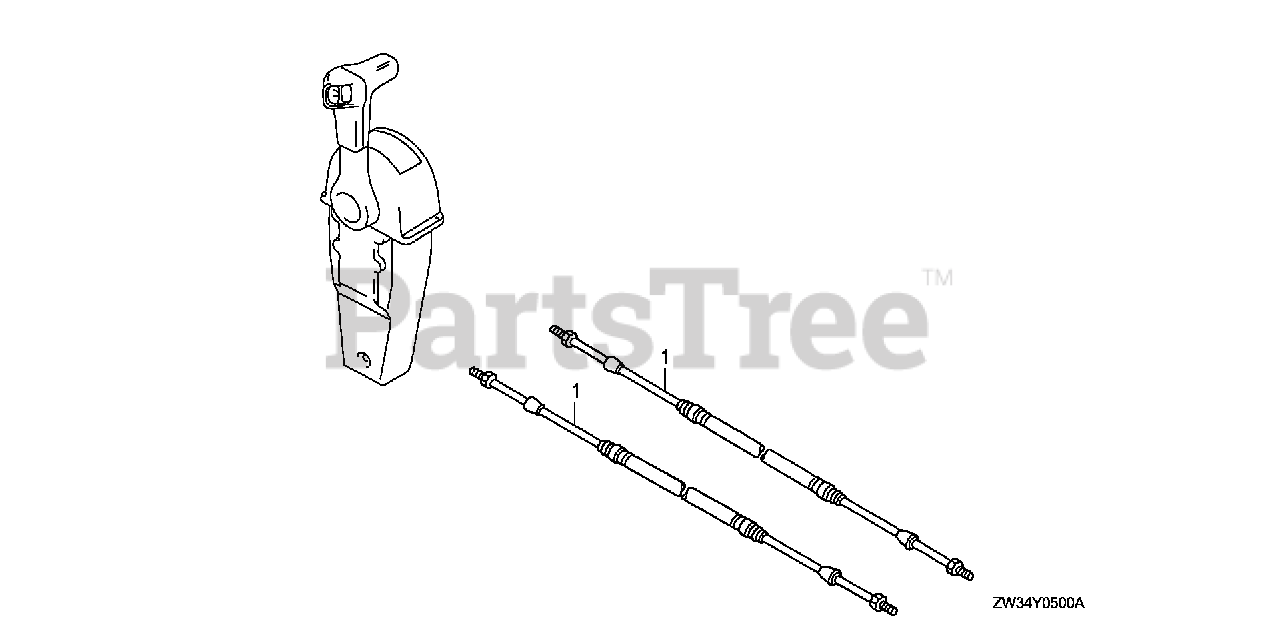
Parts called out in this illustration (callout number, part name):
1	CABLE, REMOTE CONTROL (10') (LOW FRICTION)
1	CABLE ASSY., PUSH-PULL (33C-5FT)
1	CABLE, REMOTE CONTROL (11') (LOW FRICTION)
1	CABLE ASSY., PUSH-PULL (33C-6FT)
1	CABLE, REMOTE CONTROL (12') (LOW FRICTION)
1	CABLE ASSY., PUSH-PULL (33C-7FT)
1	CABLE, REMOTE CONTROL (13') (LOW FRICTION)
1	CABLE ASSY., PUSH-PULL (33C-8FT)
1	CABLE, REMOTE CONTROL (14') (LOW FRICTION)
1	CABLE ASSY., PUSH-PULL (33C-9FT)
1	CABLE, REMOTE CONTROL (15') (LOW FRICTION)
1	CABLE ASSY., PUSH-PULL (33C-10FT)
1	CABLE, REMOTE CONTROL (16') (LOW FRICTION) (NOT AVAILABLE)
1	CABLE ASSY., PUSH-PULL (33C-11FT)
1	CABLE, REMOTE CONTROL (17') (LOW FRICTION)
1	CABLE ASSY., PUSH-PULL (33C-12FT)
1	CABLE, REMOTE CONTROL (18') (LOW FRICTION) (NOT AVAILABLE)
1	CABLE ASSY., PUSH-PULL (33C-13FT)
1	CABLE, REMOTE CONTROL (19') (LOW FRICTION)
1	CABLE ASSY., PUSH-PULL (33C-14FT)
1	CABLE, REMOTE CONTROL (20') (LOW FRICTION) (NOT AVAILABLE)
1	CABLE ASSY., PUSH-PULL (33C-15FT)
1	CABLE, REMOTE CONTROL (21') (LOW FRICTION)
1	CABLE ASSY., PUSH-PULL (33C-16FT)
1	CABLE, REMOTE CONTROL (22') (LOW FRICTION) (NOT AVAILABLE)
1	CABLE ASSY., PUSH-PULL (33C-17FT)
1	CABLE, REMOTE CONTROL (23') (LOW FRICTION)
1	CABLE ASSY., PUSH-PULL (33C-18FT)
1	CABLE, REMOTE CONTROL (24') (LOW FRICTION) (NOT AVAILABLE)
1	CABLE ASSY., PUSH-PULL (33C-19FT)
1	CABLE, REMOTE CONTROL (25') (LOW FRICTION)
1	CABLE ASSY., PUSH-PULL (33C-20FT)
1	CABLE, REMOTE CONTROL (26') (LOW FRICTION)
1	CABLE ASSY., PUSH-PULL (33C-21FT)
1	CABLE, REMOTE CONTROL (27') (LOW FRICTION)
1	CABLE ASSY., PUSH-PULL (33C-22FT)
1	CABLE, REMOTE CONTROL (28') (LOW FRICTION) (NOT AVAILABLE)
1	CABLE ASSY., PUSH-PULL (33C-23FT)
1	CABLE, REMOTE CONTROL (29') (LOW FRICTION)
1	CABLE ASSY., PUSH-PULL (33C-24FT)
1	CABLE, REMOTE CONTROL (30') (LOW FRICTION) (NOT AVAILABLE)
1	CABLE ASSY., PUSH-PULL (33C-25FT)
1	CABLE, REMOTE CONTROL (31') (LOW FRICTION)
1	CABLE ASSY., PUSH-PULL (33C-26FT)
1	CABLE, REMOTE CONTROL (32') (LOW FRICTION) (NOT AVAILABLE)
1	CABLE ASSY., PUSH-PULL (33C-27FT)
1	CABLE, REMOTE CONTROL (33') (LOW FRICTION)
1	CABLE ASSY., PUSH-PULL (33C-28FT)
1	CABLE, REMOTE CONTROL (34') (LOW FRICTION) (NOT AVAILABLE)
1	CABLE ASSY., PUSH-PULL (33C-29FT)
1	CABLE, REMOTE CONTROL (35') (LOW FRICTION)
1	CABLE ASSY., PUSH-PULL (33C-30FT)
1	CABLE ASSY., PUSH-PULL (33C-31FT)
1	CABLE ASSY., PUSH-PULL (33C-32FT)
